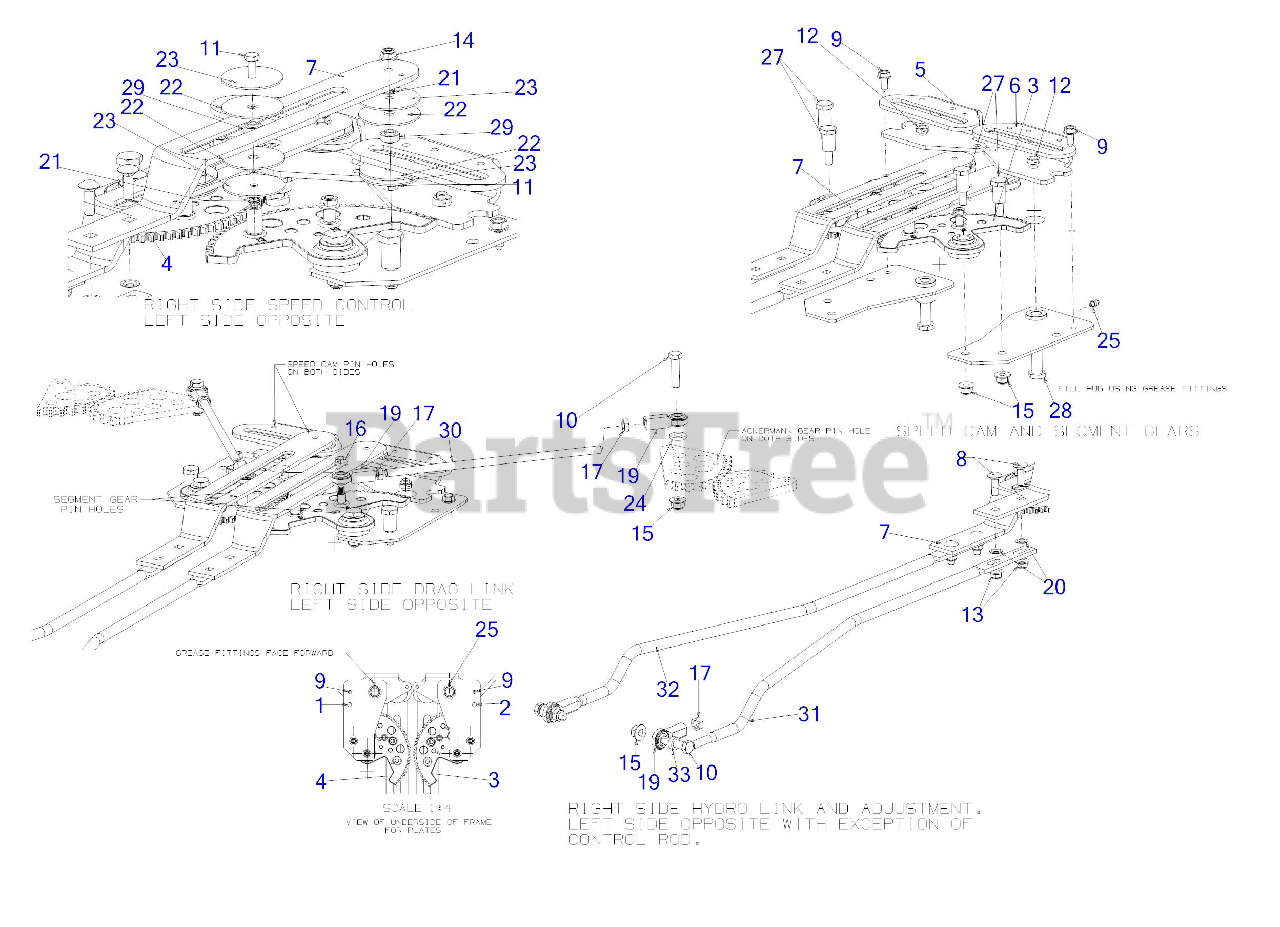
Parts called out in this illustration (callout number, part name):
1	STEERING SUPPORT PLATE (RH)
2	STEERING SUPPORT PLATE (LH)
3	STEERING GEAR ASSEMBLY (LH)
4	STEERING GEAR ASSEMBLY (RH)
5	SPEED CAM PLATE (LH)
6	SPEED CAM PLATE (RH)
7	CONTROL LINK
8	CARRIAGE BOLT 5/16-18 x 1.00
9	SCREW 5/16-18 x .750
10	SCREW 3/8-16 x 1.50
11	SCREW 1/4-20X1.0 GR5
12	JAM LOCK NUT
13	FLANGE LOCK NUT 5/16-18
14	FLANGE LOCK NUT
16	FLANGE NUT
17	HEX JAM NUT 3/8X24
19	BALL JOINT (RH)
21	RETAINER-BOLT .25ID x .50OD
22	FLAT WASHER
23	FLAT WASHER
24	FLAT WASHER
25	GREASE ZERT 1/4-28
27	SHOULDER SCREW .625 x .875 x 3/18
28	SHOULDER SCREW .50
29	BALL BEARING .25 X .625
30	STEERING DRAG LINK
31	HYDRO LINK ROD (RH)
32	HYDRO LINK ROD (LH)
33	SPACER-.380 ID X.625 OD x .227
